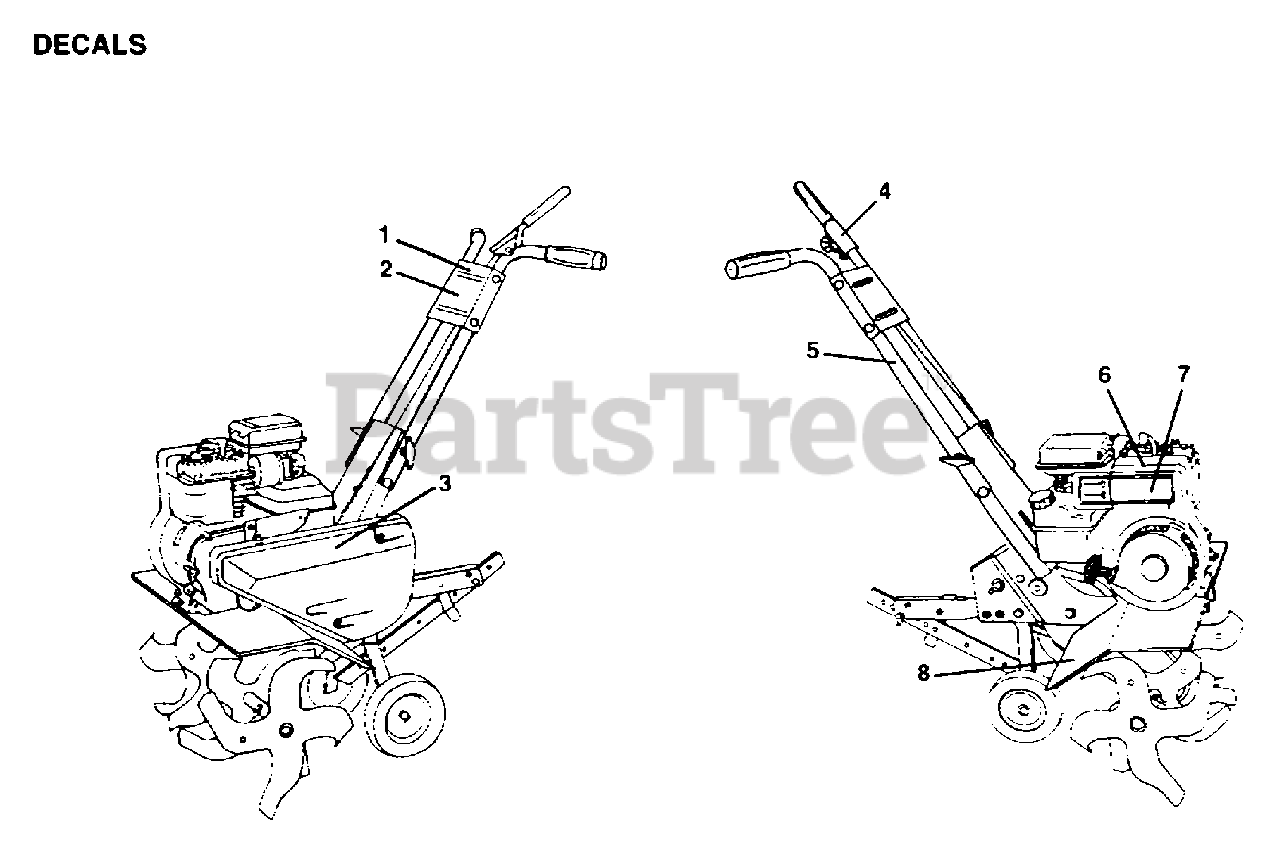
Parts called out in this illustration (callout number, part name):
1	DECAL.PNL.CNT
3	DECAL.GUARD.BELT
4	DECAL TI
5	DECAL TI
7	"DECAL,ENG HP"
8	DECAL TI
